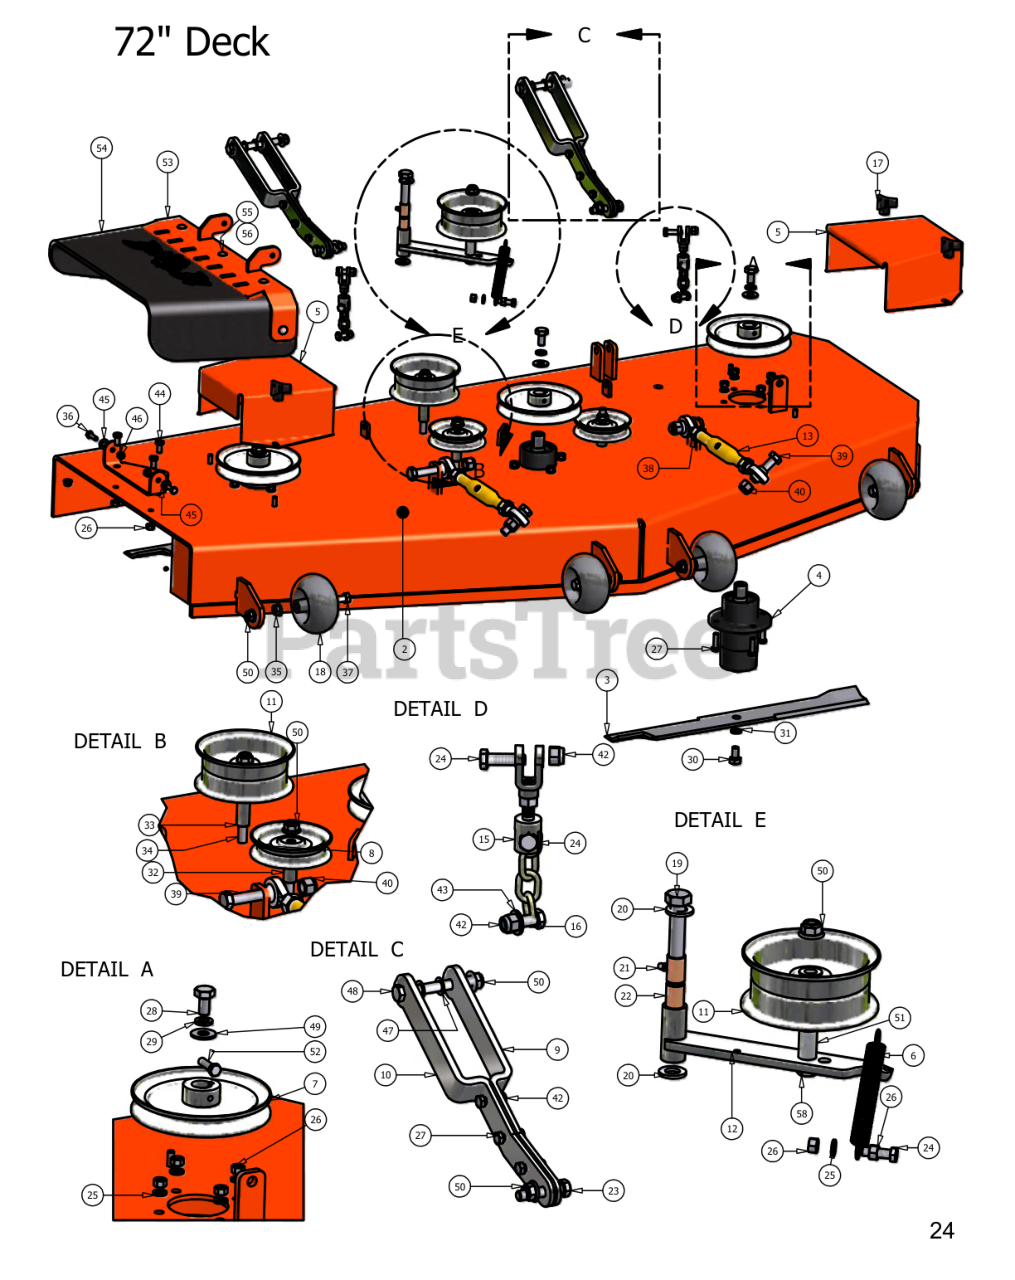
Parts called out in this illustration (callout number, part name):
1	72" Deck Belt
3	72" Frsion Blade
5	Pulley Guard
6	Deck Idler Spring
7	7" Deck Pulley
8	4 3/4" Idler Pulley
9	Deck Support Arm (Right)
10	Deck Support Arm(Left)
11	5 3/4" Flat Idler Pulley
12	Deck Idler Arm
13	Turnbuckle
14	Female Yoke
17	5/16" Knob
18	Anti-Scalp Roller
19	5/8" x 4" Hex Bolt
20	.635 ID Plastic Washer
21	Grease Fitting (Drive-in Type)
22	5/8" ID x 1 1/8" Brass Bushing
23	1/2" x 2 1/2" Hex Bolt
24	3/8" x 1 1/4" Hex Bolt
25	3/8" Lock Washer
26	3/8" Hex Nut
27	3/8" x 1 1/4" Hex Bolt
28	1/2" x 1 1/2" Fine Thread Bolt
29	1/2" Lock Washer
30	5/8" x 1 1/2" Fine Thread Bolt
31	5/8" Lock Washer
32	1 1/2" Pulley Spacer
33	1 3/4" Pulley Spacer
34	1/2" x 3 1/2" Bolt
35	1/2" Flange Nut
36	5/16" x 1" Hex Bolt
37	1/2" x 4" Bolt
38	3/4" Left Handed Nut
39	5/8" x 2 1/2" Hex Bolt
40	5/8" STD NC Nylock Nut
41	3/8" Fine Threaded Jam Nut
42	3/8" Flat Washer
43	3/8" x 3/4" Hex Bolt
44	.360 ID Plastic Washer
45	5/16" Nylock Nut
46	1/2" Brass Washer
47	1/2" x 4 1/2" Bolt
48	1/2" Cupped Washer
49	1/2" Flange Lock Nut
50	1 1/4" Pulley Spacer
51	3/8" Hex Bolt
52	2007 Hanger Plate
53	Rubber Side Discharge
54	5/16" x 1 1/2" Carriage Bolt
55	5/16" Nylock Flange Nut
56	2007 Lower Hanger Plate
57	1/2" x 3" Bolt
